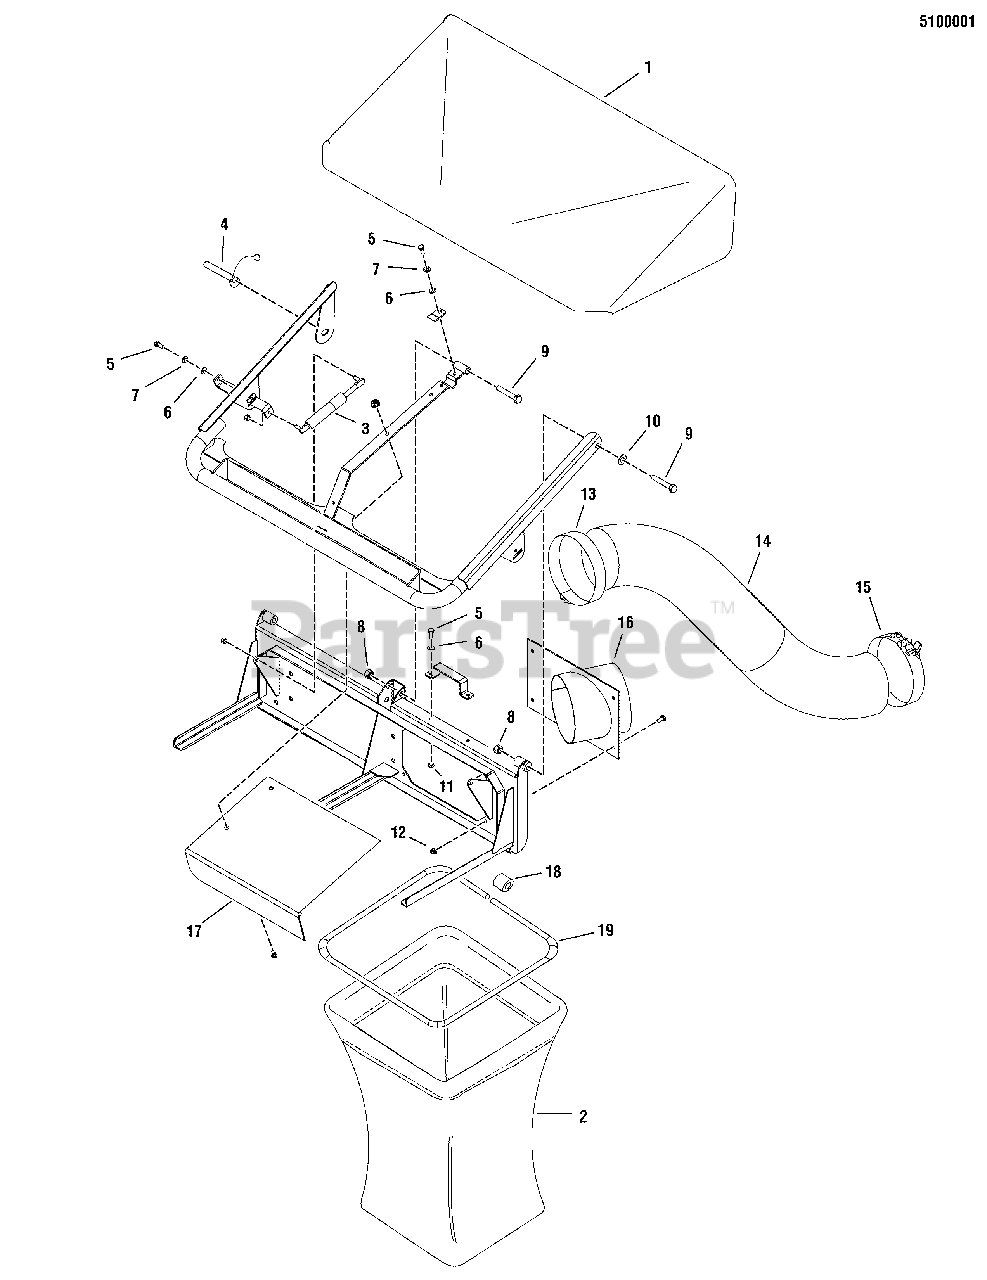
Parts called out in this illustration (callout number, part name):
1	2-BAG AIR DOME
2	CATCHER BAG W/ HANDLE
3	GAS CYLINDER
4	DETENT PIN W/ LANYARD
5	BOLT, 5/16-18 X 3/4 GD5
6	WASHER, 5/16" SAE
7	WASHER, 5/16" LOCK
8	NUT, 1/2-13 HEX NYLON LOCK
9	BOLT, 1/2-20 X 3" GD5
10	WASHER, 1/2 SAE, YZ (15124)
11	NUT, 5/16-18 HEX NYLON LOCK
12	NUT, 5/16-18 HEX NYLOCK FLANGE
13	CLAMP, HOSE, UPPER
15	CLAMP, HOSE, LOWER
16	WELD, INLET BLOWER 2-BAG BLACK
17	BAFFLE
18	BAG FRAME CONNECTOR, PLASTIC
19	BAG FRAME
